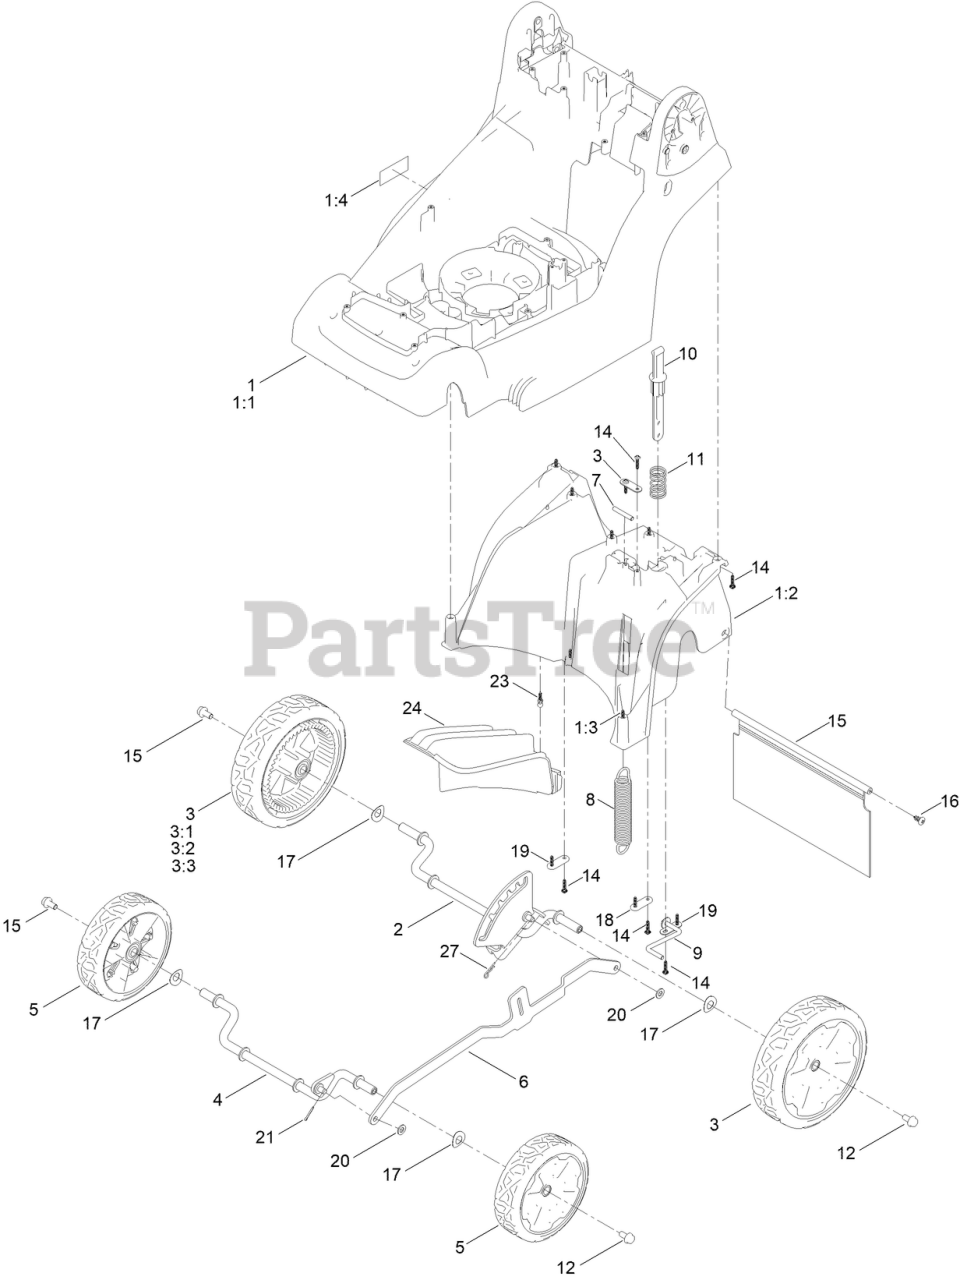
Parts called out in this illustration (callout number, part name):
1	DECK, GLUED (36)
1:1	DECK-36CM
1:2	36CM 4 WHEEL REAR CHASSIS MOULDING
1:4	DECAL - SAFETY
2	REAR AXLE FRAME, ASSY, WHEEL
3	WHEEL-REAR ASSEMBLY
3:1	WHEEL-TORO REAR
3:2	BEARING
3:3	REAR WHEEL TRIM - TORO
4	FRONT AXLE, ASSEMBLY
5	WHEEL-TORO FRONT ASSEMBLY
6	CON-ROD, 4 WHEEL
7	BAR, SPRING MOUNT
8	HOC SPRING, 4 WHEEL
9	HOC WIRE ASM
10	HOC BUTTON PLUNGER
11	SPRING, HOC BUTTON
12	BOLT, M8 X 1.25, 16MM
15	SHIELD-TRAILING, 36CM
16	SCREW-PTH
17	WAVE WASHER, FRONT WHEELS
18	AXLE PLATE
19	AXLE PLATE, SMALL
20	WASHER-PLAIN
21	COTTER PIN
23	PIN, RETAINING, MULCH PLUG
24	MULCH PLUG
27	COTTER PIN
